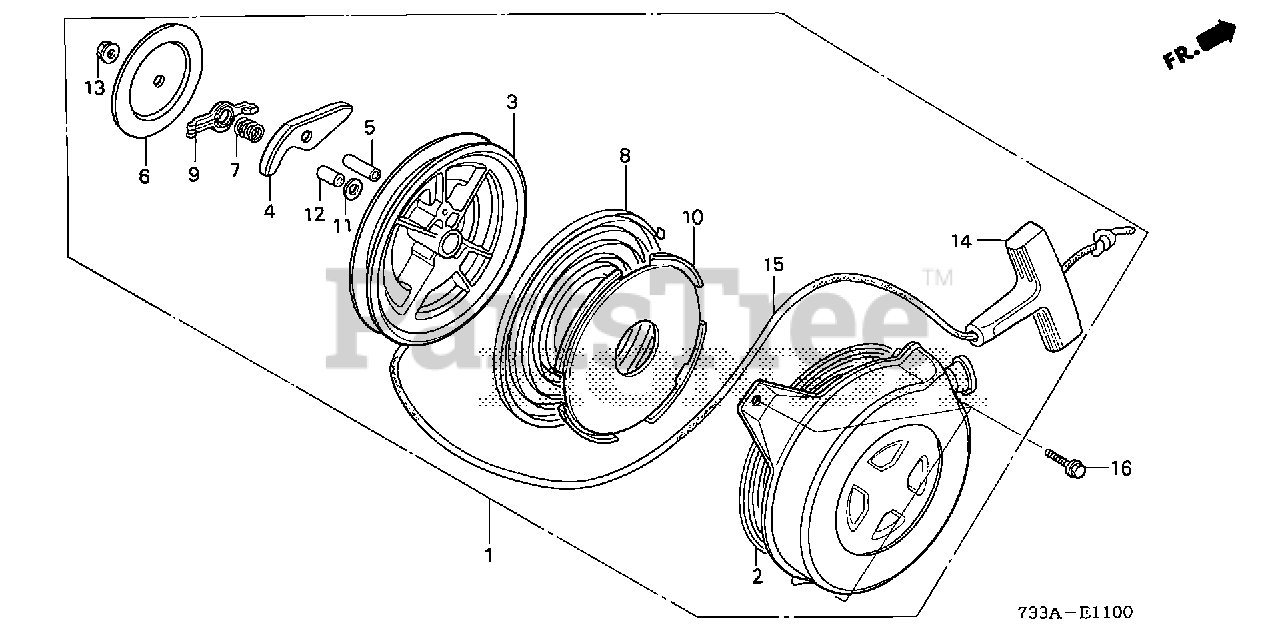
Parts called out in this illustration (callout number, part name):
1	STARTER ASSY., RECOIL *R8* (BRIGHT RED)
2	CASE, RECOIL STARTER *R8* (BRIGHT RED)
3	PULLEY, RECOIL STARTER
4	RATCHET, STARTER
5	PIN, STARTER RATCHET
6	PLATE, FRICTION
7	SPRING, FRICTION
8	SPRING, RECOIL STARTER
9	GUIDE, RATCHET
10	CASE, RECOIL STARTER SPRING
11	WASHER, STARTER
12	SHAFT, SUB
14	KNOB, RECOIL STARTER
15	ROPE, RECOIL STARTER
16	BOLT, FLANGE (6X8)
